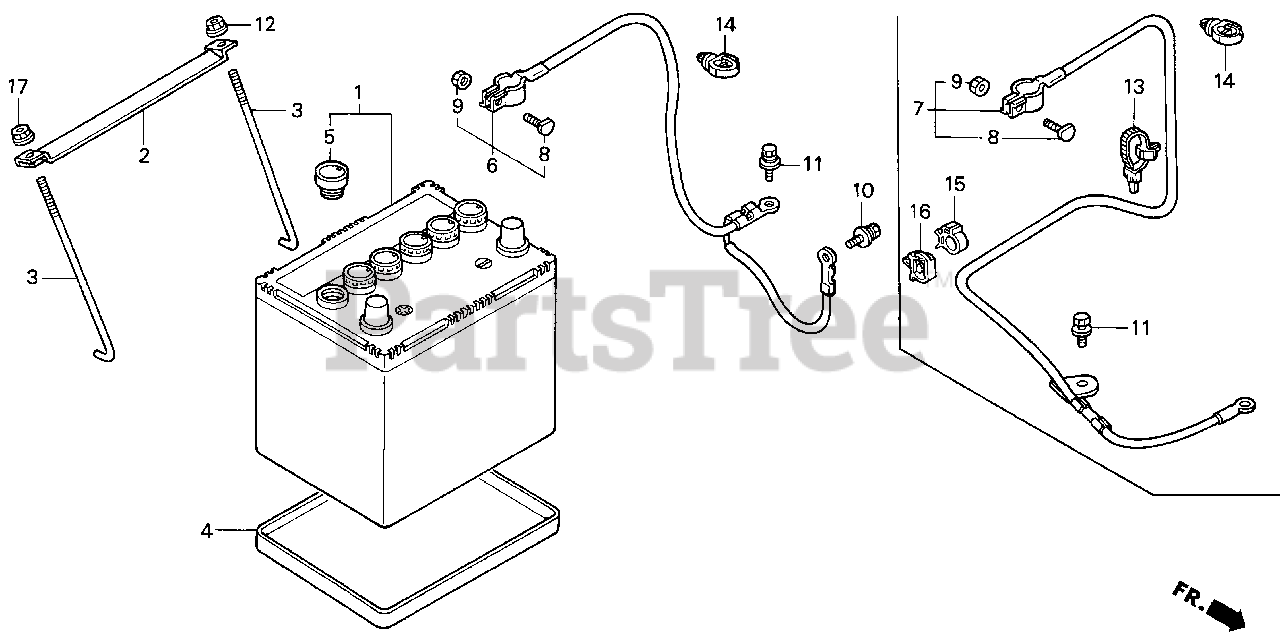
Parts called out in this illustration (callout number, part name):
1	BATTERY ASSY. (32A19RT-S) (YUASA)
2	PLATE, BATTERY SETTING
3	BOLT, BATTERY SETTING (215MM)
3	BOLT A, BATTERY SETTING
4	TRAY, BATTERY
5	PLUG, VENT (YUASA)
7	CABLE ASSY., GROUND
8	BOLT, BATTERY TERMINAL (SUMITOMO)
9	NUT, BATTERY TERMINAL (SUMITOMO)
11	BOLT, GROUND (6X16) (SN)
12	NUT, FLANGE (6MM)
13	BAND, WIRE HARNESS (WHITE)
14	CLIP, WIRE HARNESS (25MM)
15	CLIP, CABLE (8MM)
16	CLIP, WIRE HARNESS
17	NUT, FLANGE (6MM)
